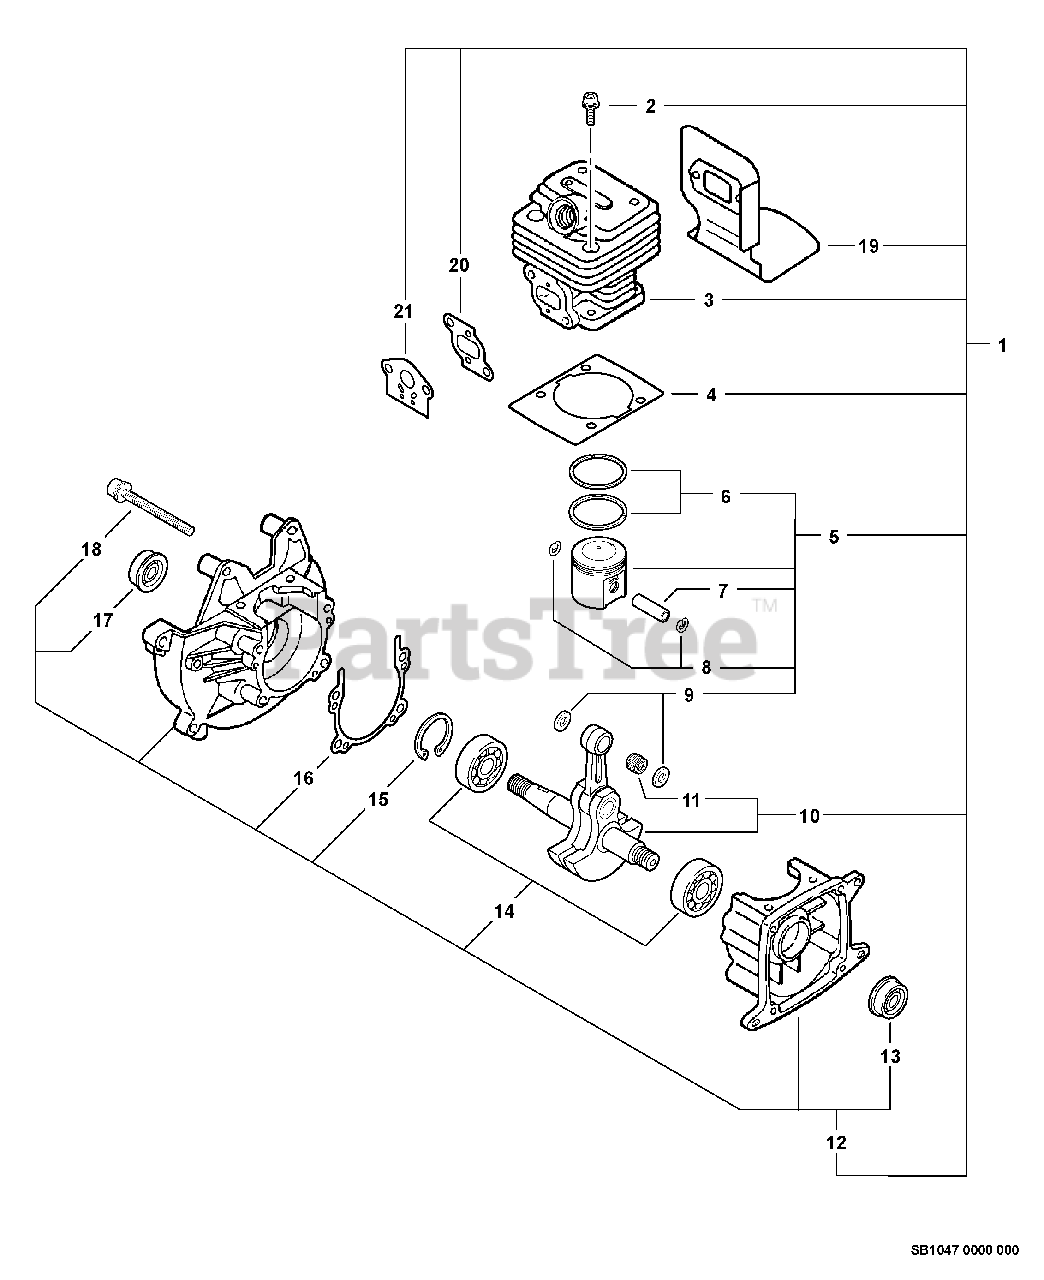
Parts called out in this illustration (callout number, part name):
1	SHORT BLOCK
2	BOLT 5×22
3	CYLINDER
4	GASKET, CYLINDER
5	PISTON KIT
6	RING, PISTON
7	PIN, PISTON
8	RING, SNAP
9	WASHER, THRUST
10	BEARING, NEEDLE 8
11	CRANKSHAFT ASSY
12	CRANKCASE KIT
13	SEAL, OIL 12
14	BEARING, BALL 6001
15	RING, SNAP 28
16	GASKET, CRANKCASE
17	BOLT 5×25
18	SEAL, OIL 12
19	HEAT SHIELD, EXHAUST
20	GASKET, INTAKE
21	GASKET, CARBURETOR
